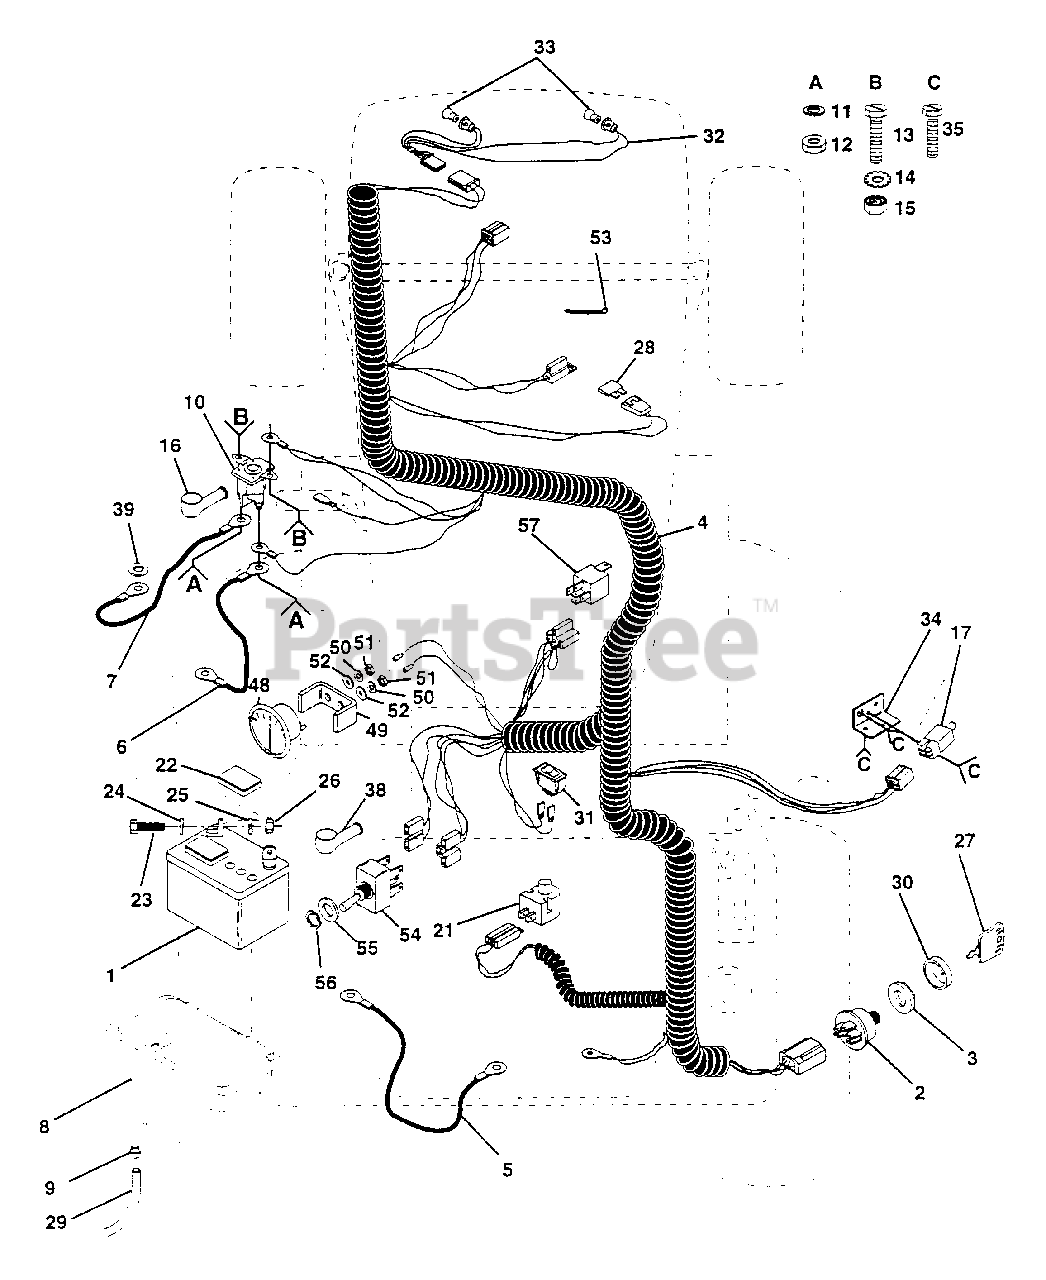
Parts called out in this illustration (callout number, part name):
1	Battery 12 Volt 30 Amp
2	Switch Ign 5 Term Wo/wash/nut
3	Nut Ignition
4	Harness Ign Kohl Fend HI Amm
5	Cable Ground 6ga 12"black
6	Cable Battery 6ga 39" Red
7	Cable Battery 6ga 22" red
8	Case Battery w/o Lid
9	Clamp Hose Olive
10	Solenoid
11	Washer Lock 1/4
12	Nut Jam Hex 1/4-20 Unc
13	Bolt Fin Hex 1/4-20uncx1/2 Gr5
14	Washer Lock Ext Tooth 1/4
15	Nut Keps Hex lid-20 Unc
16	Cover Terminal Red
17	Switch Interlock Clutch
21	Switch Plunger Nc Gray
22	Caps Battery 20/25/30 Amp
23	Bolt Hex Hd 1/4-20unc X 3/4
24	Washer 9/32 X 5/8 X 16 Ga
25	Washer Lock Hvy Helical 1/4
26	Nut Fin Hex 1/4-20 Unc
27	Key Ign Molded Generic
28	Fuse 30 Amp Auto Green
29	Tube Plastic 12"
30	Cover Sw Key Blk 1 25 Text Sit
31	Switch Light Blk Blk Red
32	Harness Socket Light
33	Bulb, Light r 1141
34	Bracket Switch Clutch
35	Screw Hex Tapping # 10-24 X 1/2
38	Cover, Terminal
39	Washer. Lock Int. Tooth 1/4
48	Ammeter Round 15 Amp
49	Bracket Ammeter 2 242 X 1 180
50	Washer Lock
52	Washer 7/32 X 1/2 X 18 Ga
53	Tie Cable
54	Switch PTO
55	Washer 17/32 x 3/4 x 16 Ga.
56	Nut Hex 1/2-28 Unf
57	Relay Assembly
